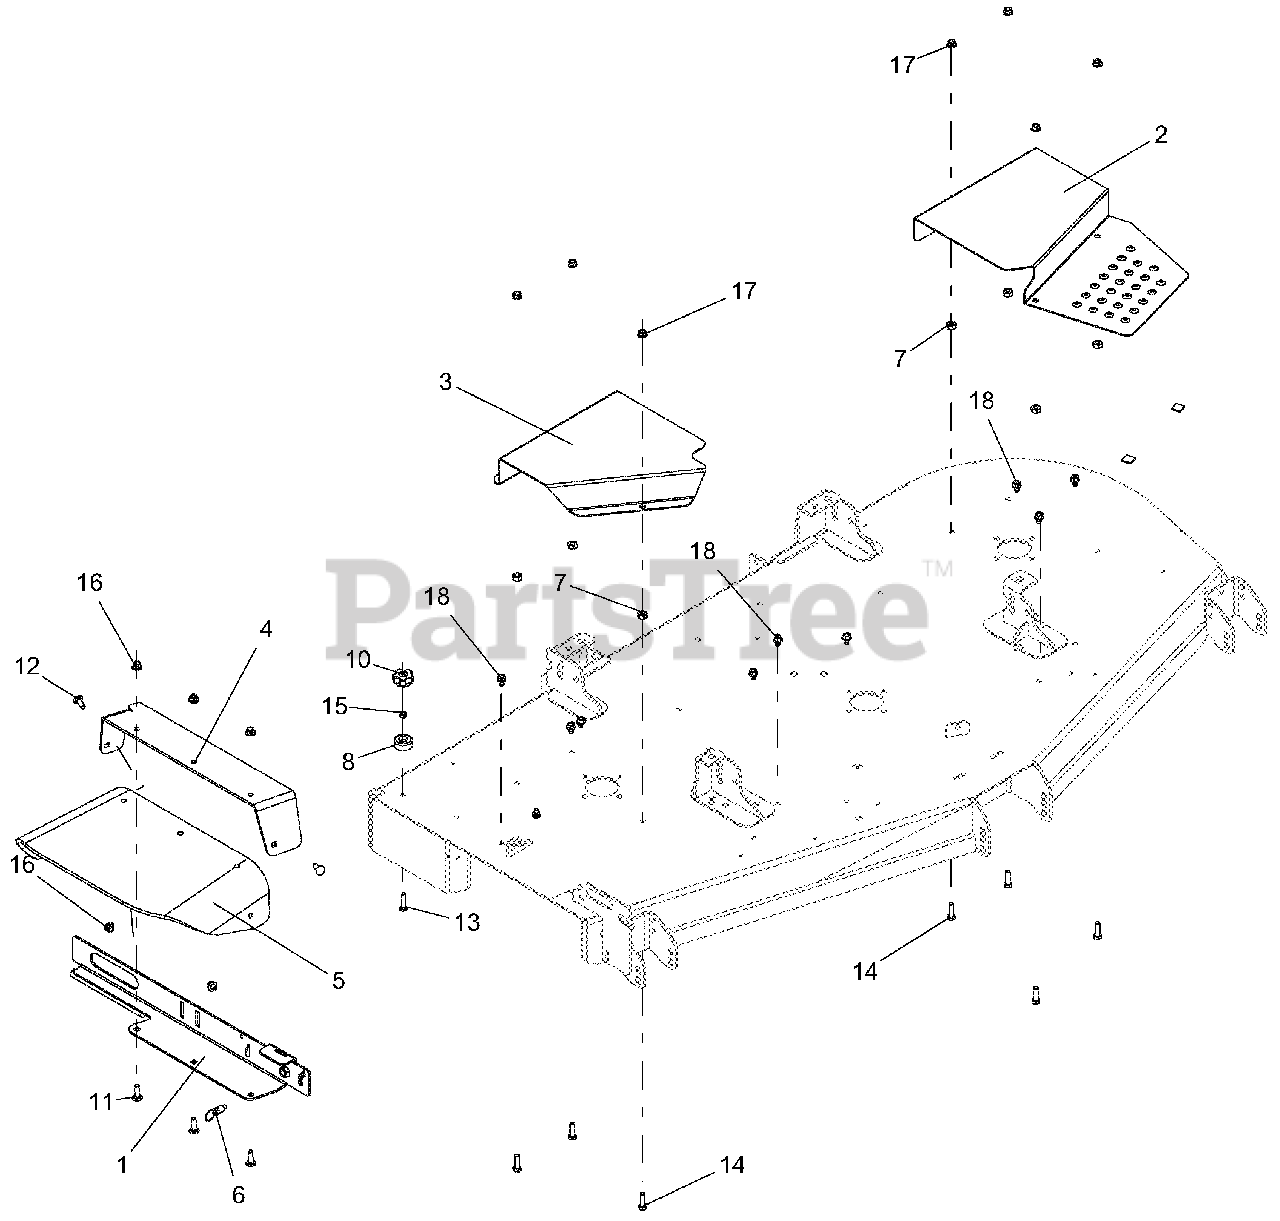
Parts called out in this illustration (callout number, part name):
1	WLDMT, 66"-72" DISCH CHUTE MTG-RED
2	GUARD, 72" LH DECK BELT-RED
3	GUARD, 72" RH DECK BELT-RED
4	SUPPORT, CHUTE MOUNTING BRACKET-RED
5	CHUTE, RUBBER DISCHARGE
6	PULL PIN,.50-13THDX.310 PLNGR
7	NUT-HEAVY HEX .38-16 YWZC
8	BUMPER, RECESSED 1.50 X .63 W/.31 HOLE
10	KNOB, CLAMPING
11	BLT-RDHDSQNK .38-16X1.25 G5 YWZC
12	BLT-RDHDSQNK .38-16X1.00 G5 YWZC
13	BLT-RDHDSQNK .31-18X1.50 G5 YWZC
14	BLT-HEX .38-16X1.25 GR5 YWZC
15	NUT-LK-CTR .31-18 YWZC
16	NUT-LK-NYL-FLG .38-16 YWZC
17	@NUT-SPNLK-FLG .375-16 YWZC
18	SCR-TAP .38-16X.50 HWH TR YWZ
